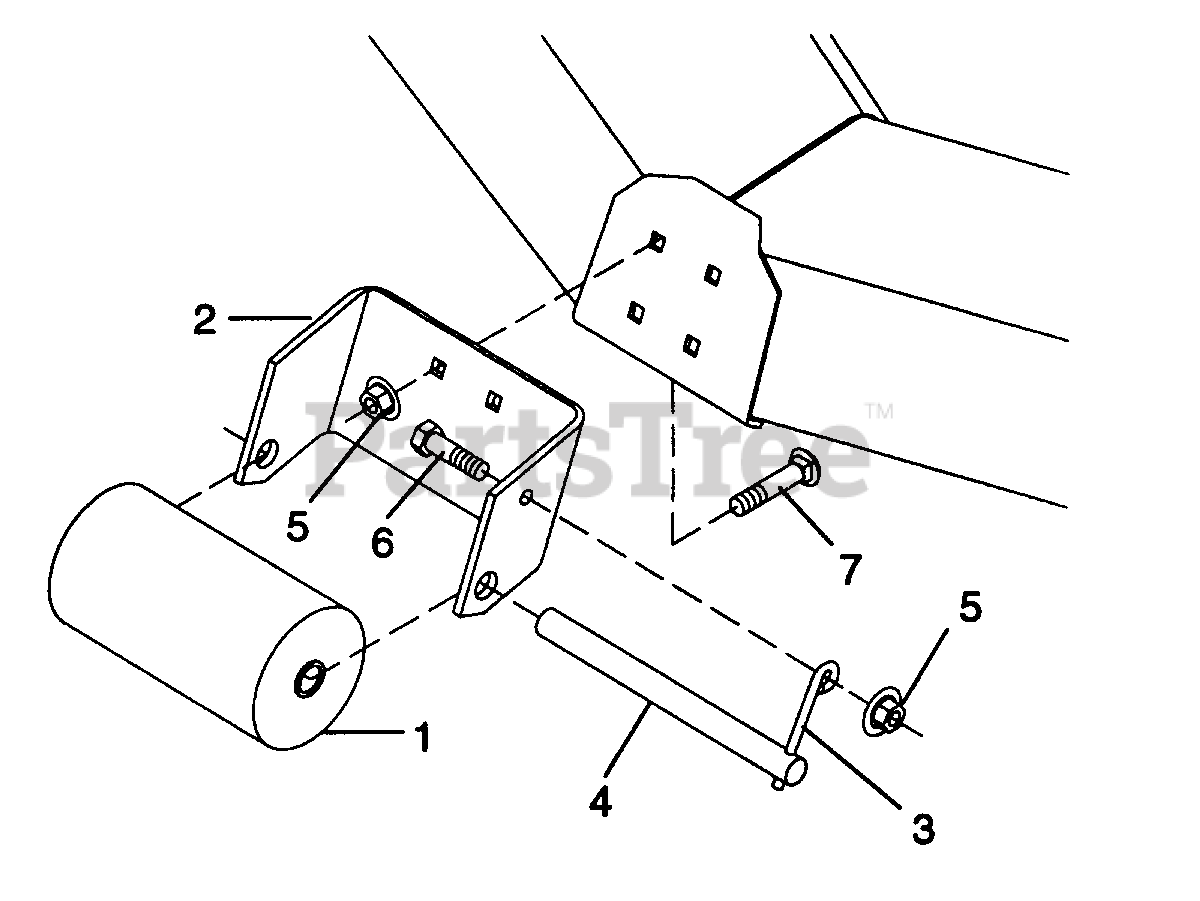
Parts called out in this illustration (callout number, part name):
1	Front roller
2	Roller bracket
3	.25 x 3.1 Retainer pin
4	Roller pin
5	3/8 NC Flanged hex locknut
6	3/8 NC x 1 Hex head cap screw GR5
7	3/8 NC x 1 Carriage bolt GR5
